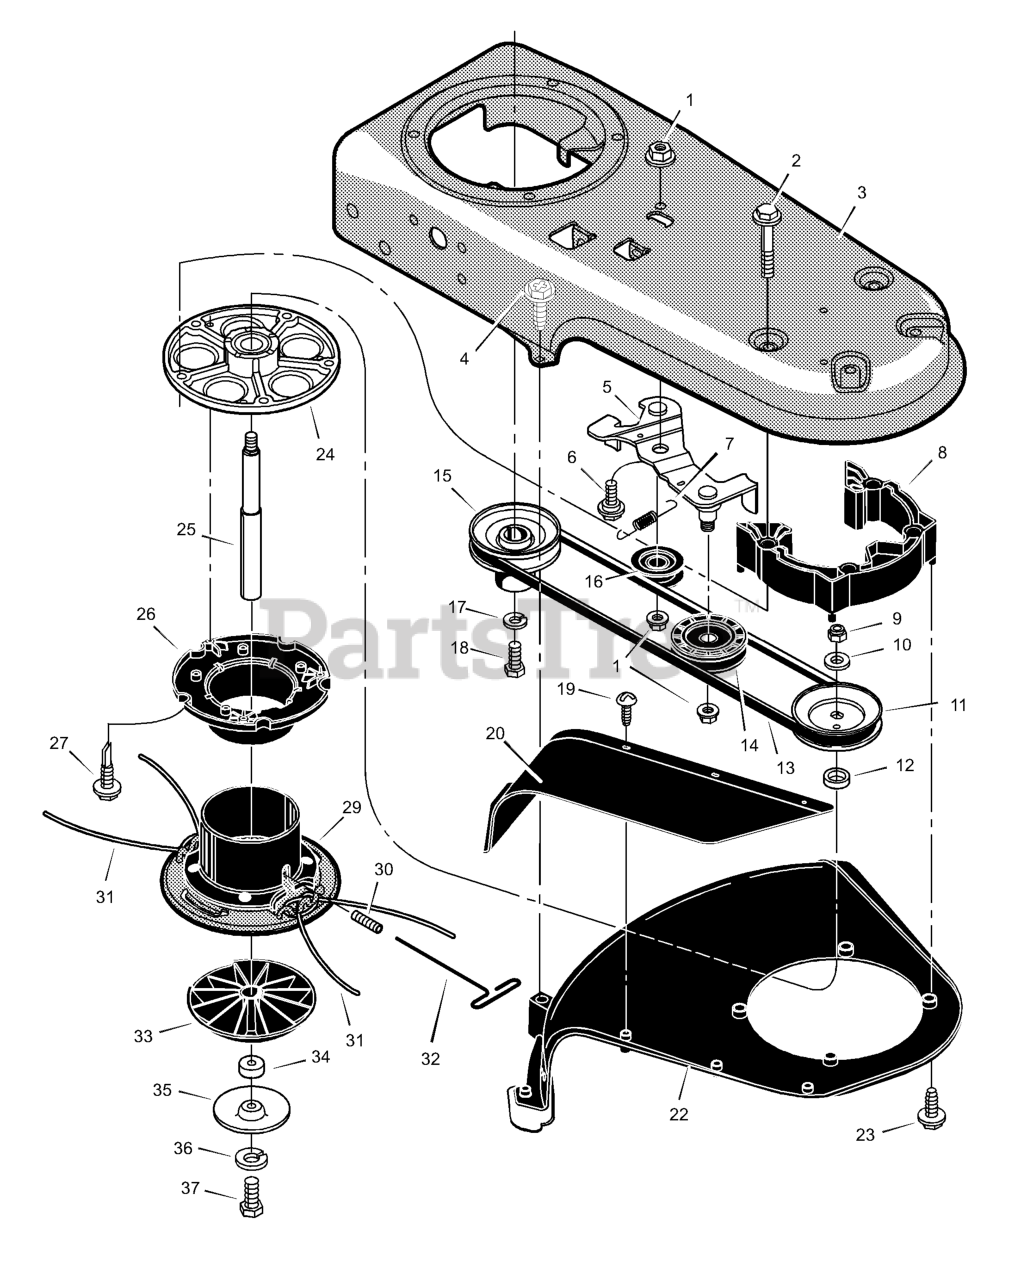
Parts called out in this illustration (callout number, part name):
2	Screw
5	Bracket, Idler Assembly
7	Spring, Extension
8	Spacer Assembly, Jackshaft
10	Washer, Flat
11	Pulley, Cutting Head
12	Spacer, Upper Pulley
13	Belt, Trimmer
14	PULLEY, IDLER, V, 1.88
15	Pulley, Engine
16	Pulley, Idler
17	Lockwasher
20	Flap, Depris
22	Shield, Trimmer
24	Housing, Jackshaft
25	Shaft, Cutting Head
26	Wrap, Weed
29	Assembly, Cutter Head & Wrap
31	Line, Trimmer 0.155 X 21.25
32	Wrench, T-Handle
33	Guide, Height
34	Spacer, Shield
35	Spacer, Abrasion
36	Washer
